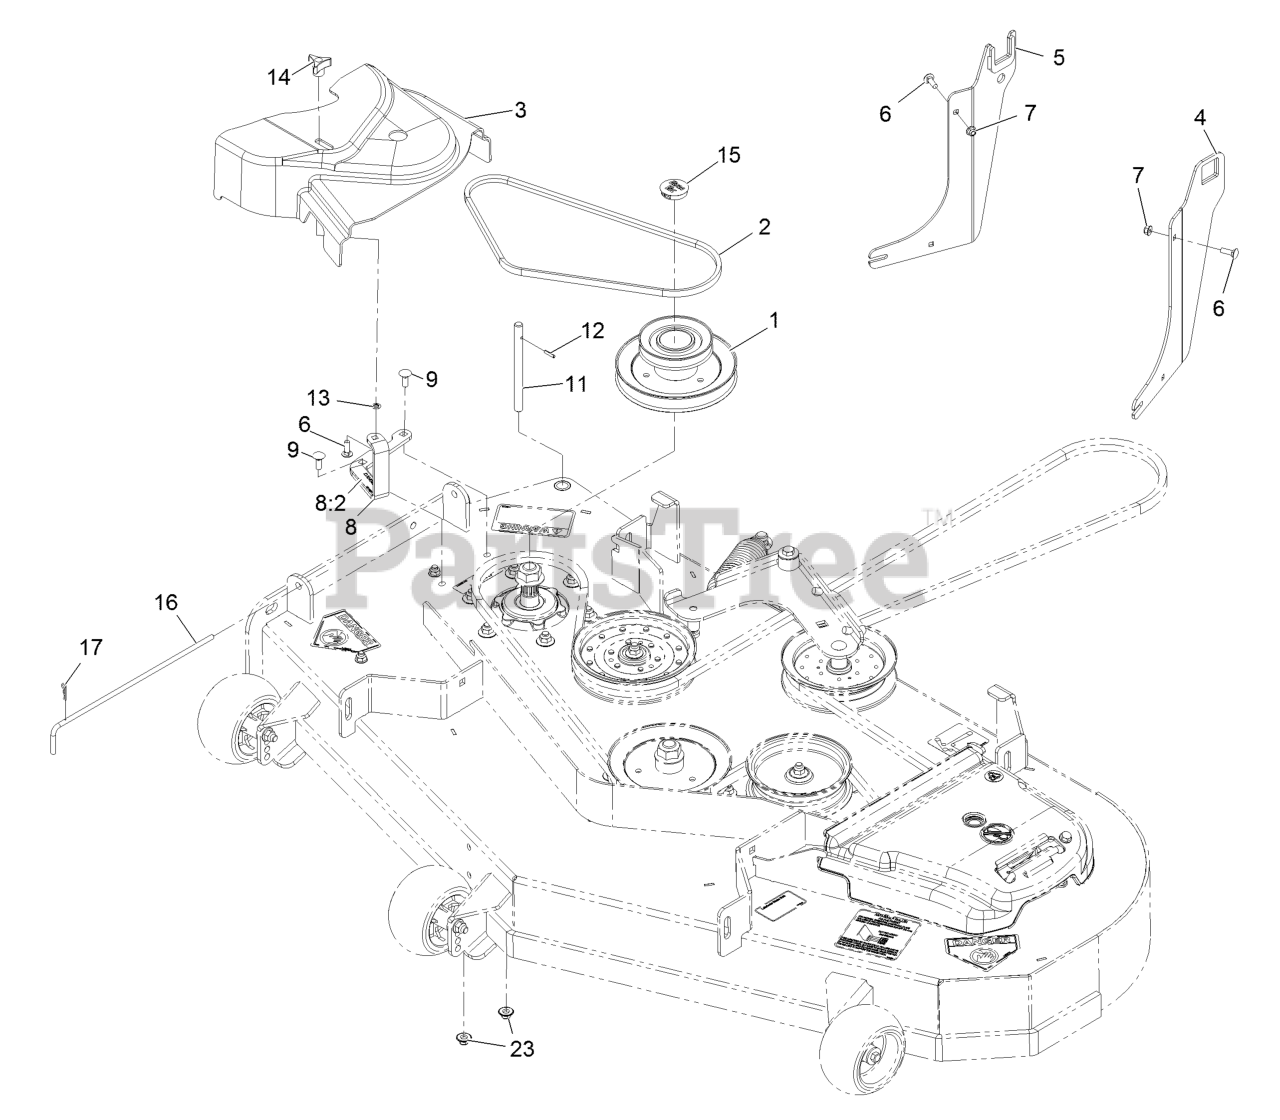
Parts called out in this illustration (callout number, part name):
1	JACKSHAFT-UV DRIVE 52 SPL
2	BELT-BLOWER
3	COVER-BELT, UV 52
4	BRACKET ASM, LH
5	BRACKET ASM, RH
6	BOLT-CARR
7	NUT-HF, NI
8	ASM-CVR BRKT W/DECAL
8:2	DECAL-COVER, MISSING
9	BOLT-CARR
11	SHAFT-CATCHER, GRASS
12	PIN-ROLL
13	RING-RETAINING, BOLT
14	KNOB-3 PRONG
15	PLUG, BLACK NYLON 1.75
16	PIN,CHUTE PIVOT
17	PIN-COTTER
23	Nut-Nyloc 3/8-16 Flg
